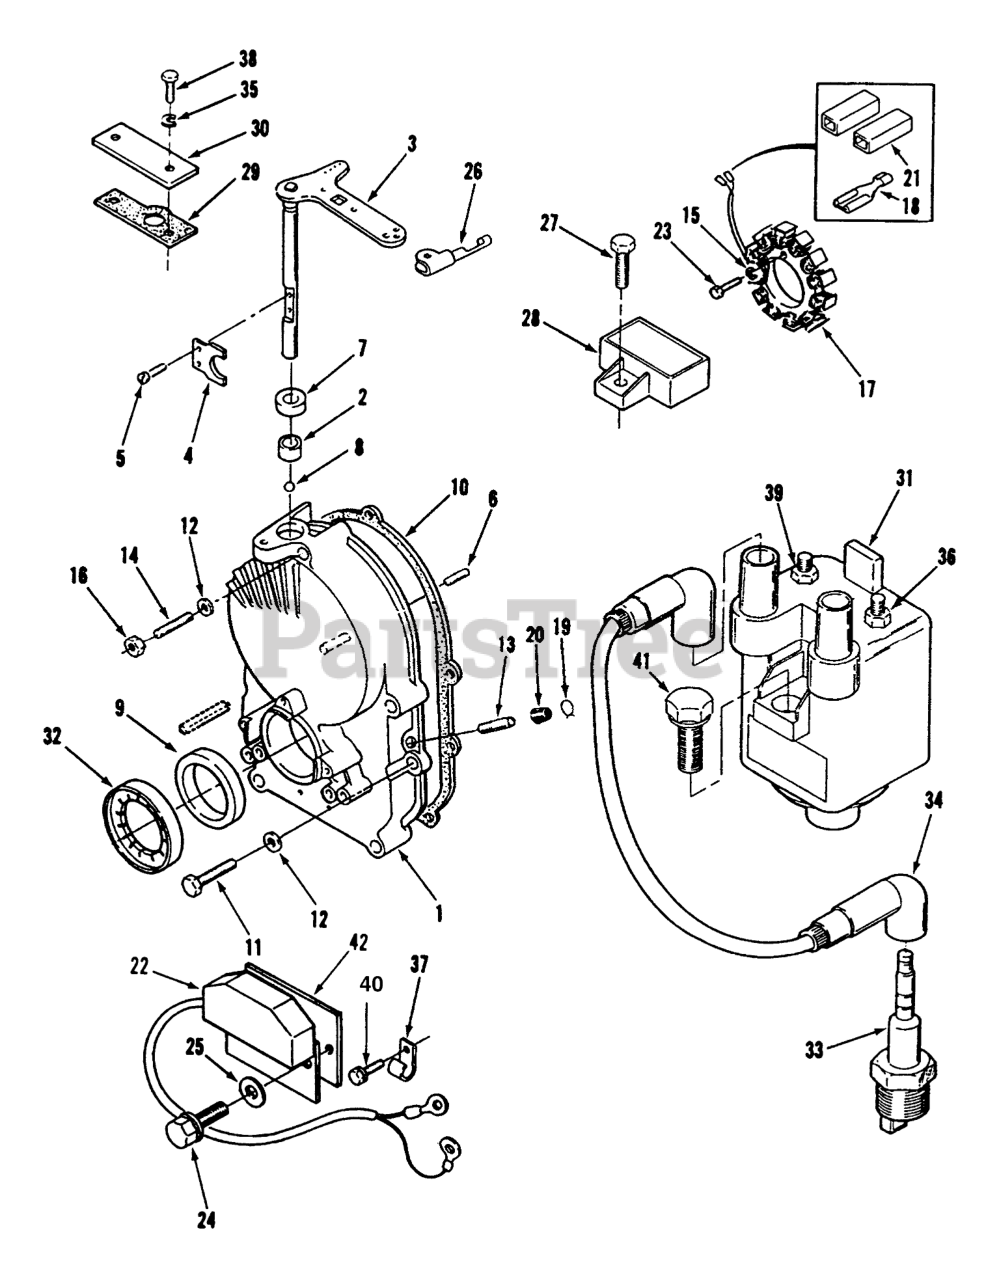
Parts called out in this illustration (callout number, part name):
1	Kit-Gearcase (Incl. Ref.#2-9, 13, 19, & 20)
2	BEARING
3	SHAFT AND ARM
5	SCREW-PAN HD
6	PIN-DOWEL
10	Gasket
11	HEX-HEAD CAP SCREW
12	WASHER
13	TUBE-PORT, VACUUM
14	STUD-GEAR COVER
15	WASHER-LOCK
16	NUT-GEAR COVER
17	KIT - STATOR
18	TERMINAL
19	CLAMP
20	CAP-FUEL OUTLET
21	BODY-TERM. CONNECTOR KIT
22	CONTROL-IGNITION
23	Screw-HH
24	Bolt
25	WASHER-LOCK
27	SCREW-HWH
28	REGULATOR
29	Gasket-Plate
30	PLATE-COVER
31	COIL-BATTERY IGNITION
32	ROTOR-IGNITION
33	SPARK PLUG
34	Wire-Plug
35	WASHER-FLAT
36	Nut
37	Clip
38	SCREW - CAP HEX HEAD
39	Nut
41	SCREW-HH
42	Insulator
